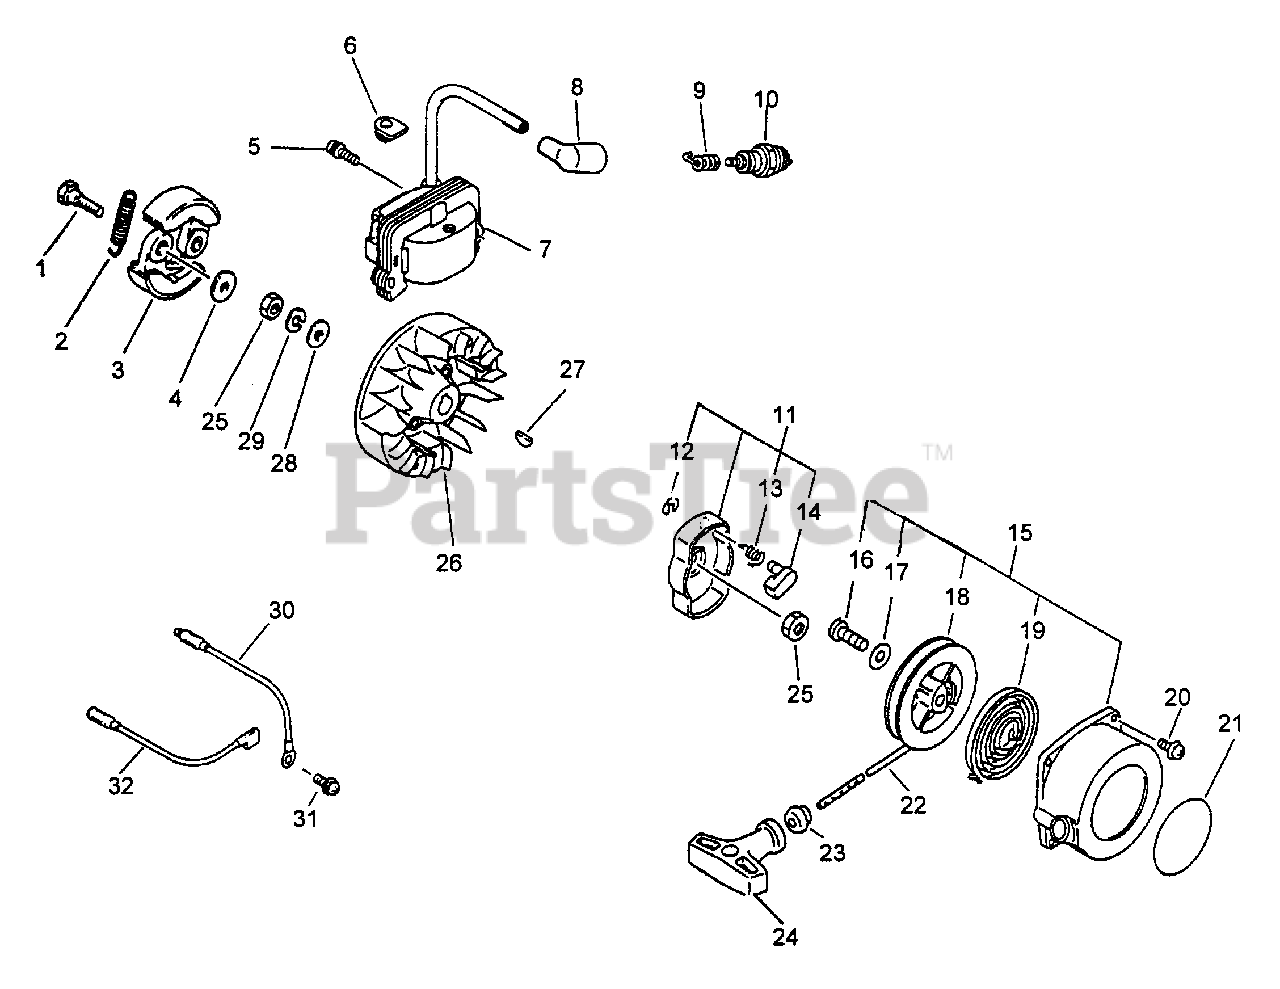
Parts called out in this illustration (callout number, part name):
1	BOLT, CLUTCH
2	SPRING, CLUTCH
3	SHOE, CLUTCH
4	WASHER - 6
5	SCREW - 5X20
7	COIL, IGNITION
8	CAP, SPARK PLUG
9	TERMINAL, SPARK PLUG CAP
10	SPARK PLUG -- BPM-7A
11	STARTER PAWL ASSY
12	RING, RETAINING - 4
13	SPRING, RETURN
14	PAWL, STARTER
15	STARTER ASSY
18	REEL, ROPE
19	SPRING, REWIND
20	SCREW - 4X14
21	LABEL - ECHO
22	RePower BULK ROPE - 200 FEET
23	GUIDE, ROPE
24	GRIP, STARTER
26	FLYWHEEL
28	WASHER - 8
29	LOCKWASHER - 8
30	LEAD - GROUND
31	SCREW - 5X10
32	LEAD - IGNITION
